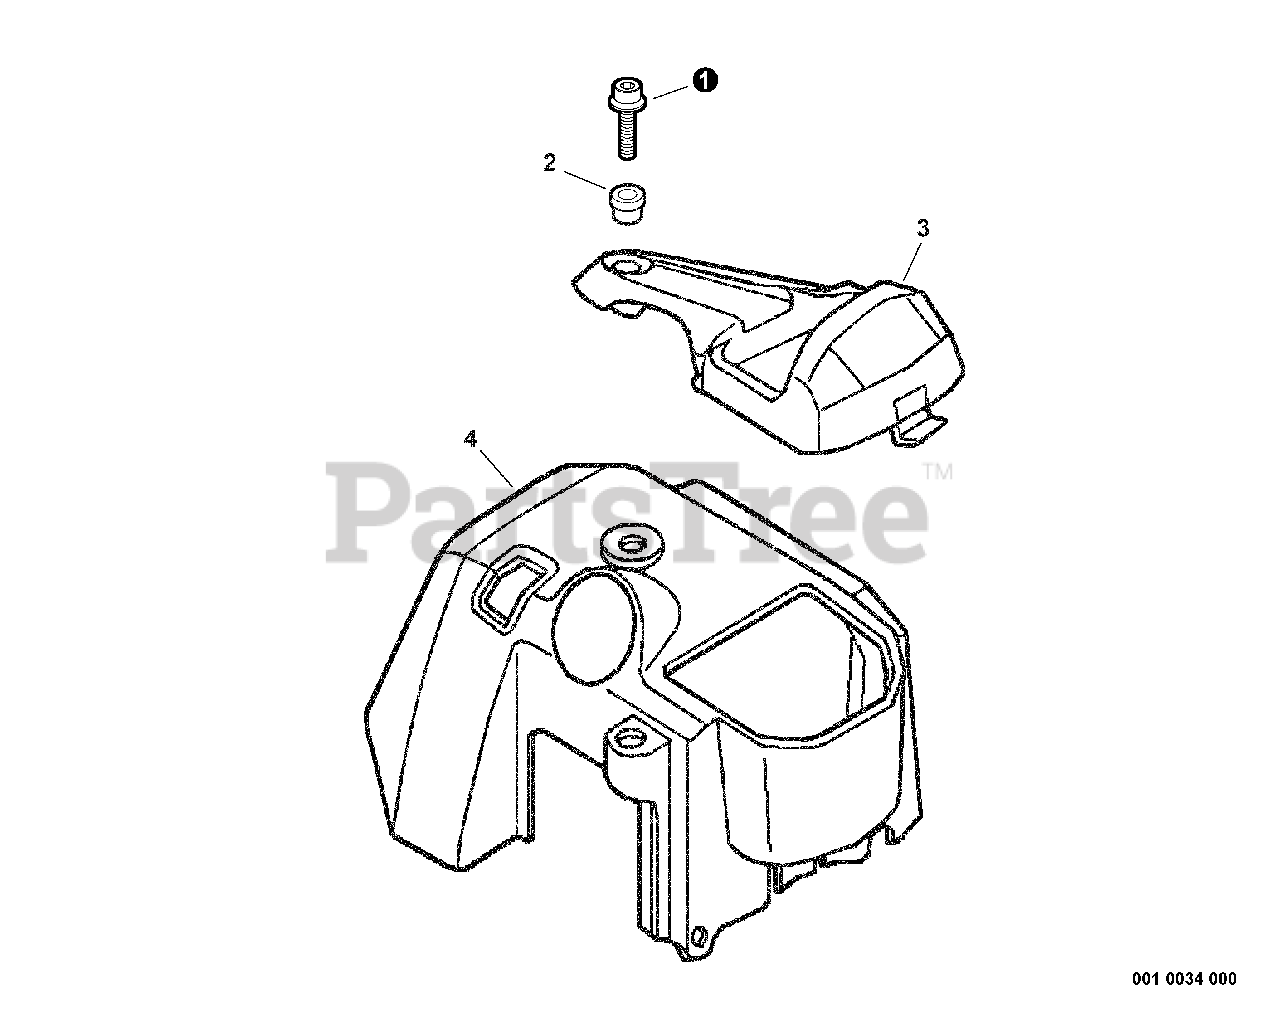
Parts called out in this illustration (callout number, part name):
1	SCREW - 5X16
2	COLLAR - 5
3	DUCT, AIR - GRAY
3	DUCT, AIR - ORANGE
4	COVER, ENGINE - GRAY
4	COVER, ENGINE - ORANGE
